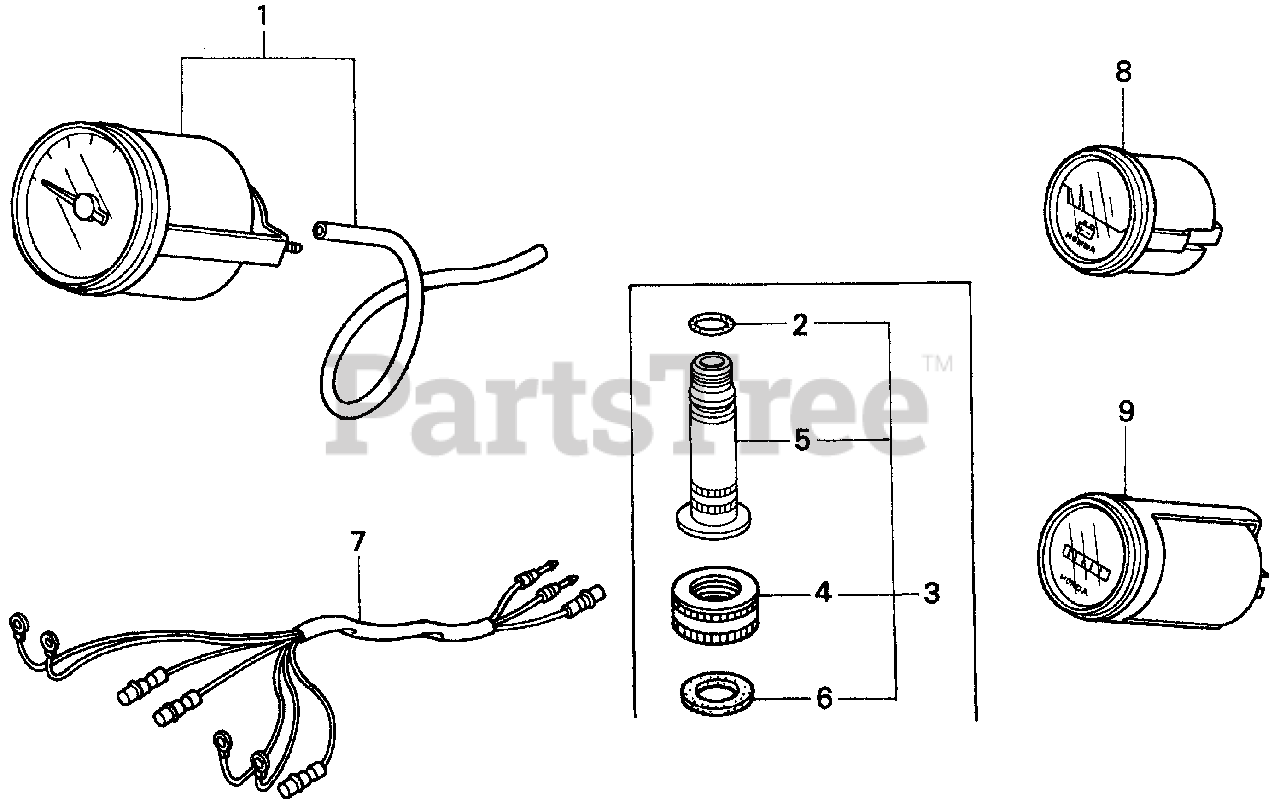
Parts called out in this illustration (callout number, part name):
1	SPEEDOMETER KIT
2	O-RING (11.8X2.4)
3	JOINT ASSY., HOSE
4	NUT, WATER MOUTH
5	JOINT ASSY., HOSE
6	SEAT, WATER MOUTH
7	HARNESS ASSY., METER (B)
8	METER ASSY., VOLT
9	METER ASSY., HOUR L.C.D.
